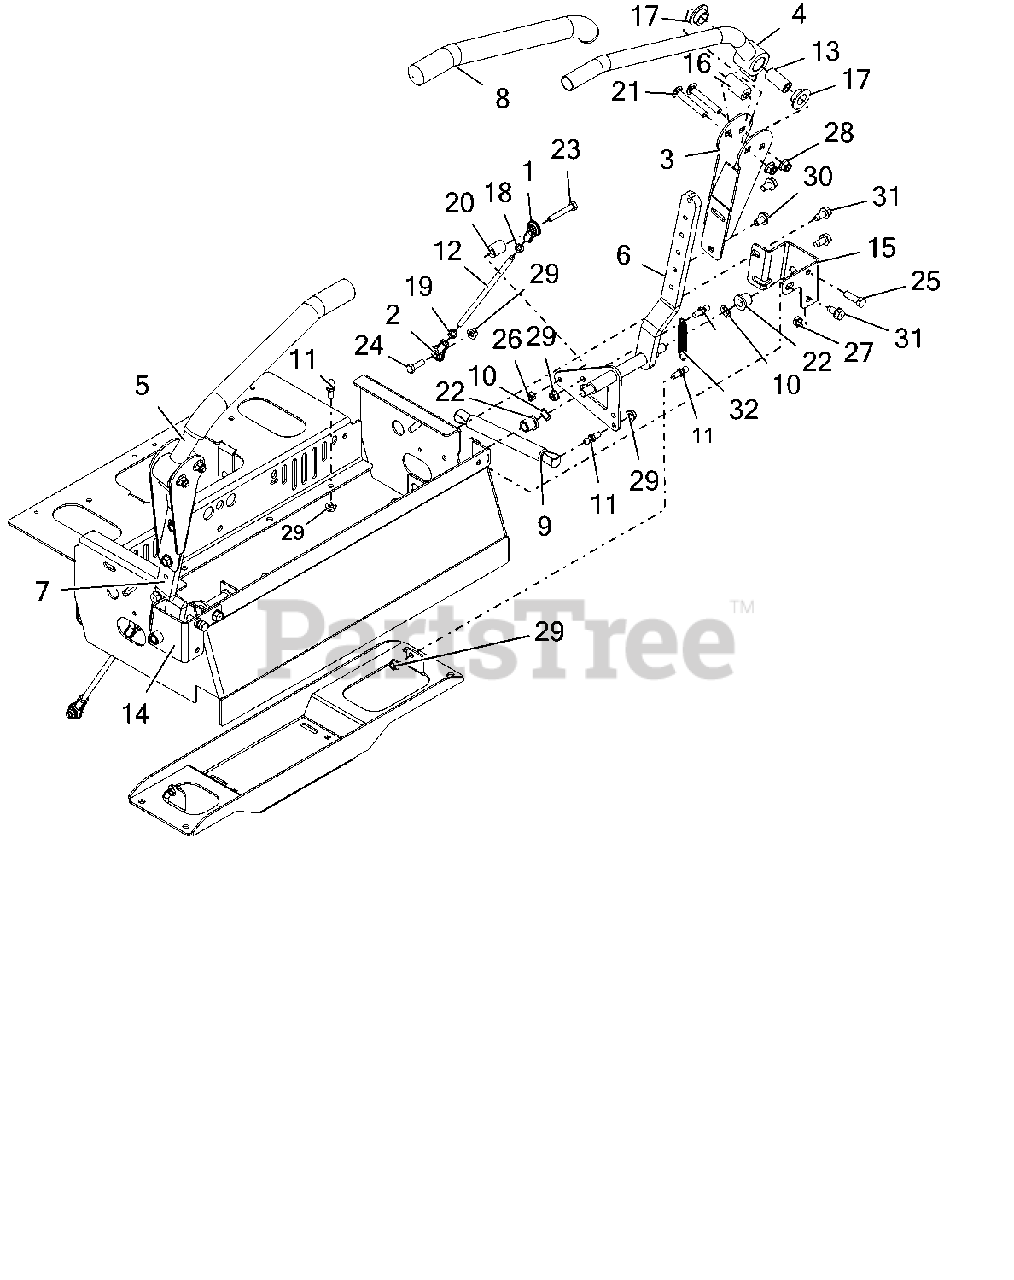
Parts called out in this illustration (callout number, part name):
1	ALIGNABALL, 5/16 RH THREAD
2	ALIGNABALL, 5/16 LH THREAD
3	WLDMT, UPPER ADJUSTABLE CONTROL ARM (BLACK)
4	WLDMT, LH CONTROL HANDLE
5	WLDMT, RH CONTROL HANDLE
6	WLDMT, LOWER LH CONTROL ARM
7	WLDMT, LOWER RH CONTROL ARM
8	GRIP, HANDLEBAR
9	DAMPER,
10	WAVE WASHER .531X.781X.125 FH
11	STUD-BALL
12	ROD, STEERING
13	SPCR, STEERING ARM
14	BRKT, PT200/400 RH CONTROL STOP (RED)
15	BRKT, PT200/400 LH CONTROL STOP (RED)
16	BSHG, ECCENTRIC .328 X .750 X 1.625
17	BSHG, FLANGE .762 X 1.48 X .44 NYLON
18	NUT-JAM
19	NUT, JAM -LH .31-24 YWZC
20	ECCENTRIC
21	BLT-RHDSSQNK .38-16X2.50 G5YZ
22	BHSG-FLG .500X.750X.750X.125
23	BLT-HEX .31-18X2.00 GR5 YWZC
24	BLT-HEX .31-18X1.00 GR5 YWZC
25	BLT-HEX .38-16X1.25 GR5 YWZC
26	NUT-LK-CTR .31-18 YWZC
27	NUT, JAM .375-16 YWZC
28	NUT-LK-NYL-FLG .38-16 YWZC
29	NUT, LK-TOP-FLG .312-18 YWZC
30	BLT-SERHFWH .38-16X.62 YWZC
31	SCR-TAP .38-16X.75 HWH TR YWZ
32	SPRG, EXTENSION
